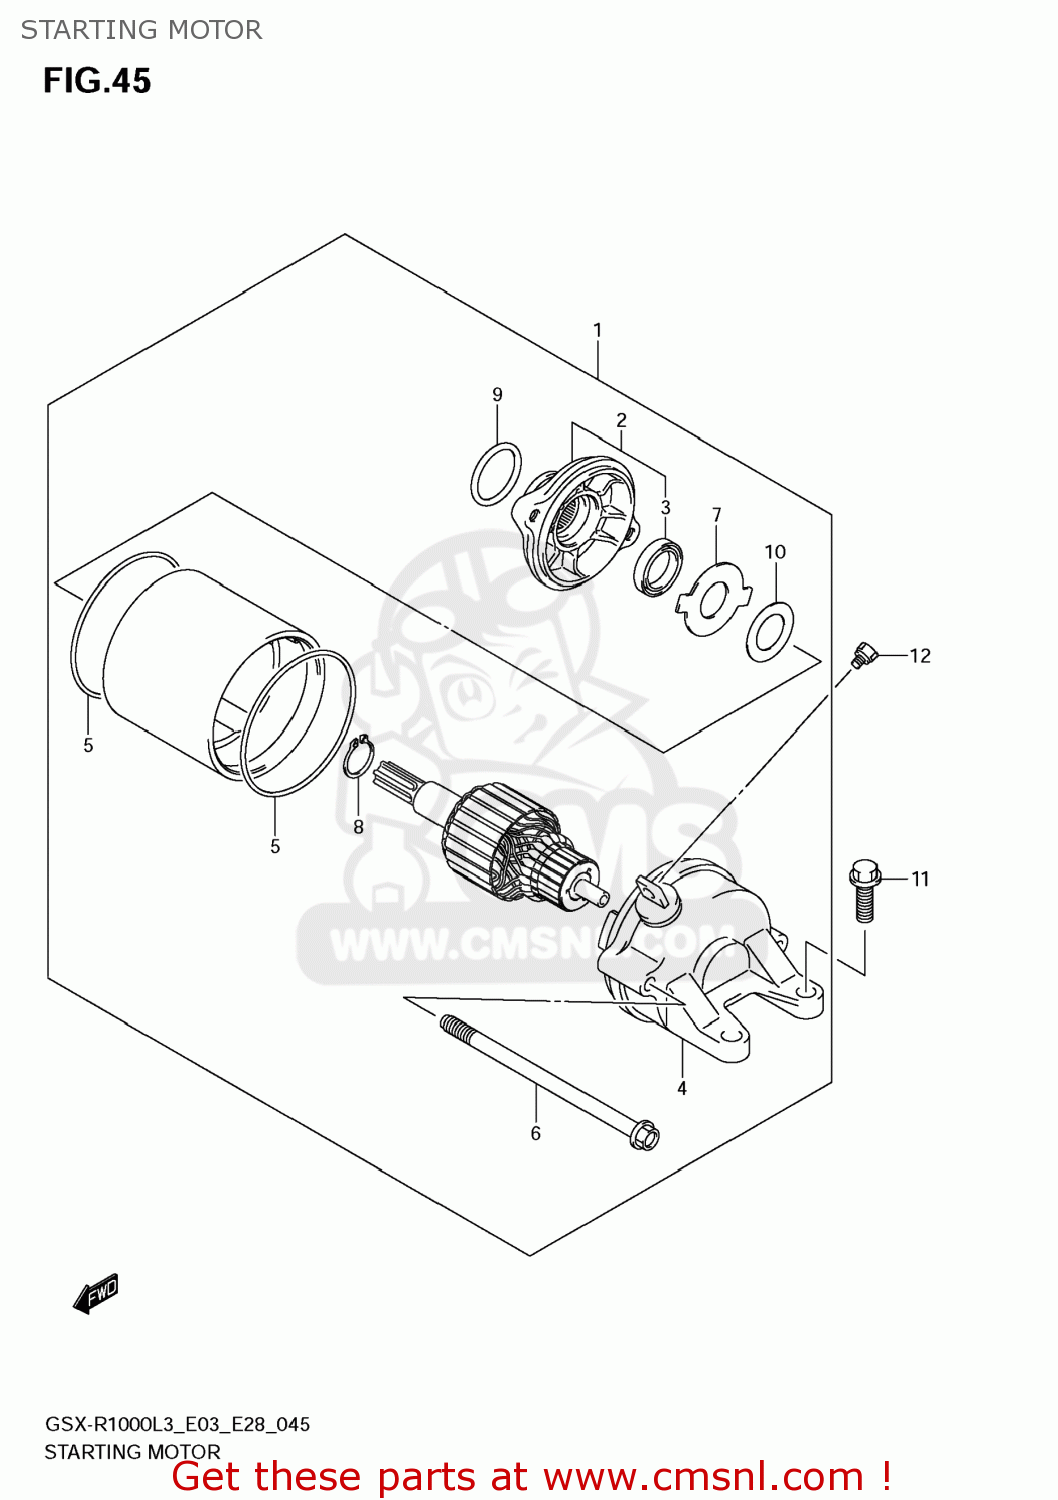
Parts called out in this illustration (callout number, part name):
1	MOTOR ASSY,STARTING
2	HOUSING ASSY
3	SEAL,OIL
4	FRAME ASSY
5	O RING
6	BOLT
7	PLATE,LOCK
8	RING,SNAP
9	O RING(COLLAR:BROWN)
10	SHIM
11	BOLT(6X20)
12	SCREW(5X8)
